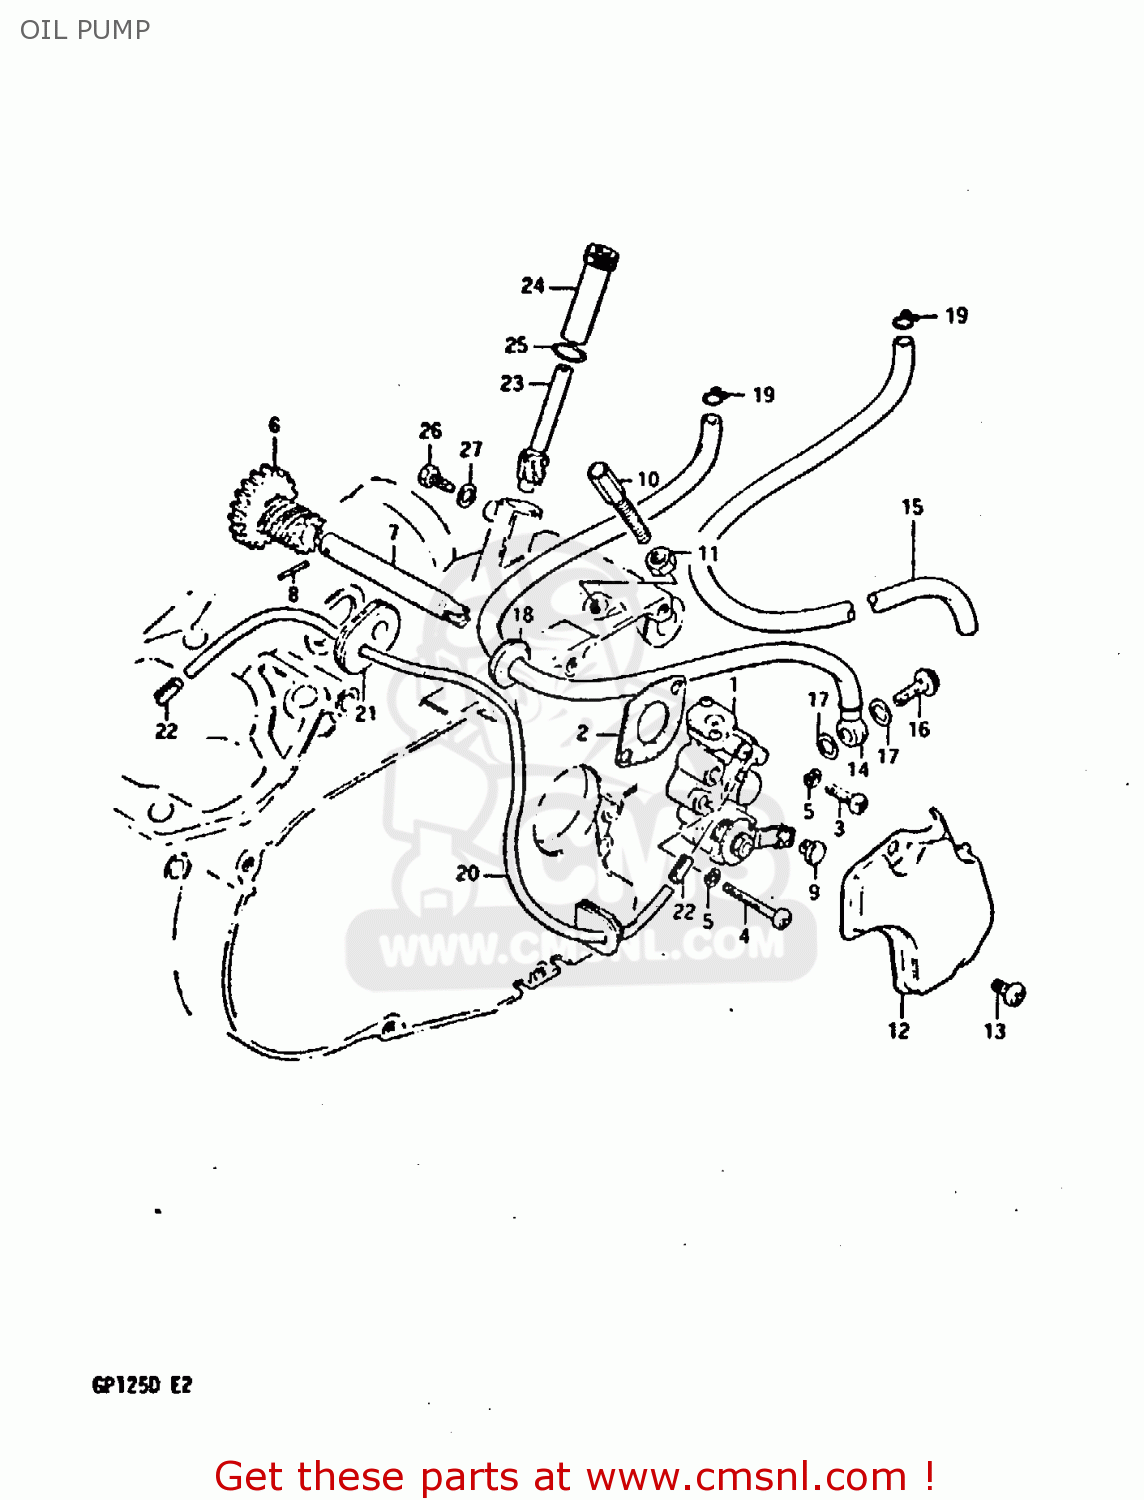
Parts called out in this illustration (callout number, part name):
1	PUMP ASSY,OIL
2	GASKET,OIL PUMP (NAS)
3	SCREW
4	SCREW
5	LOCK WASHER
6	GEAR,OIL PUMP DRIVE
7	SHAFT,OIL PUMP DRIVE GEAR
8	PIN(2.5X19.8)
9	TERMINAL,CABLE
10	BOLT
11	NUT
12	CAP,OIL PUMP INSPECTION
13	SCREW
14	HOSE,OIL NO.1
15	HOSE
16	UNION BOLT
17	GASKET(6.2X11X1).2 (NAS)
18	GROMMET
19	CLIP
20	HOSE,OIL NO.2
21	GROMMET,OIL HOSE NO.3
22	CLIP
23	GEAR, TACHO. DRIVEN (NT:10)
24	SLEEVE,TACHOMETER DRIVE GEAR
25	O RING(D:1.3,ID:9.6)
26	BOLT
27	WASHER
